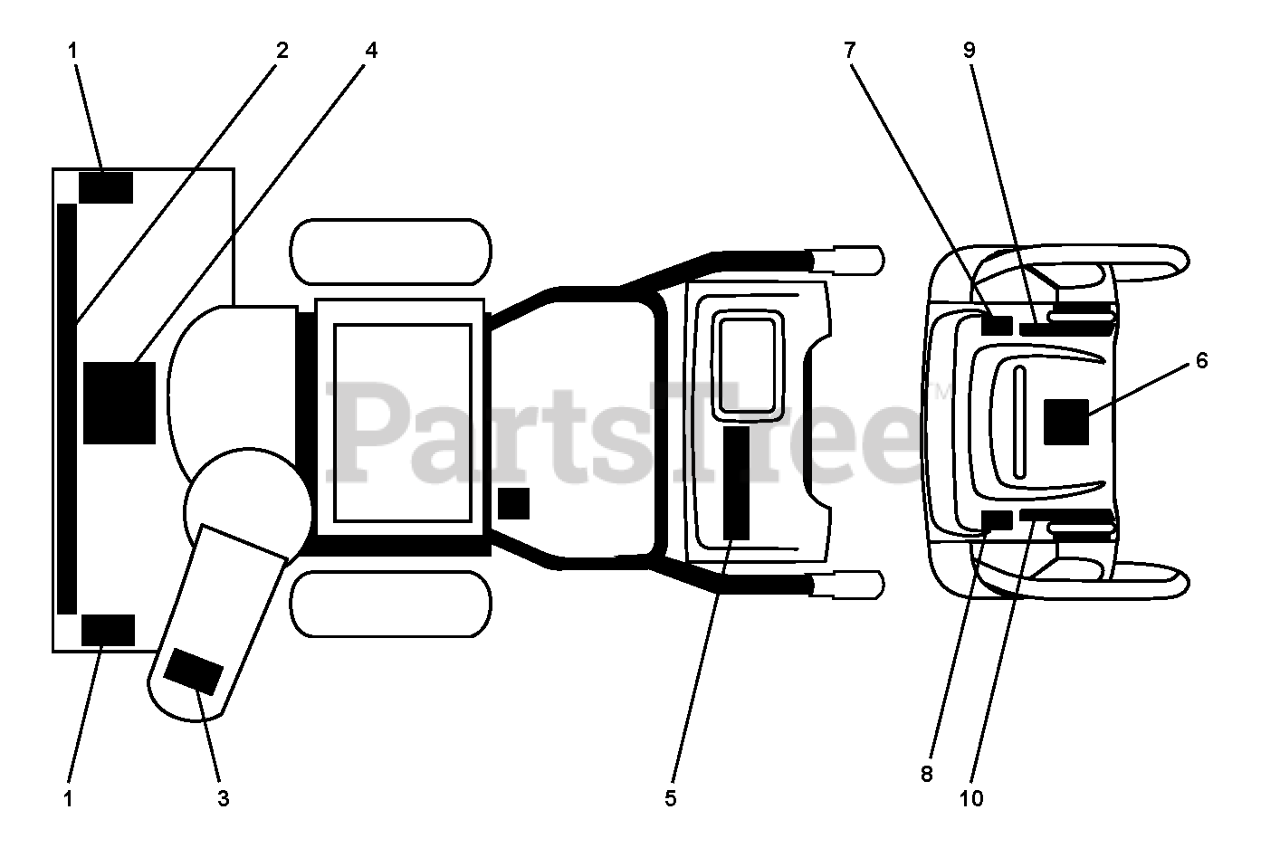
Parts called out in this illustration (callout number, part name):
1	DECAL.AUGER.SAFETY.
3	DECAL.CHUTE.SAFETY.
4	DECAL.AUGER."
6	DECAL.CONSOLE.INSTRUCTION
10	DECAL.REM.DEFLECTOR.LT
